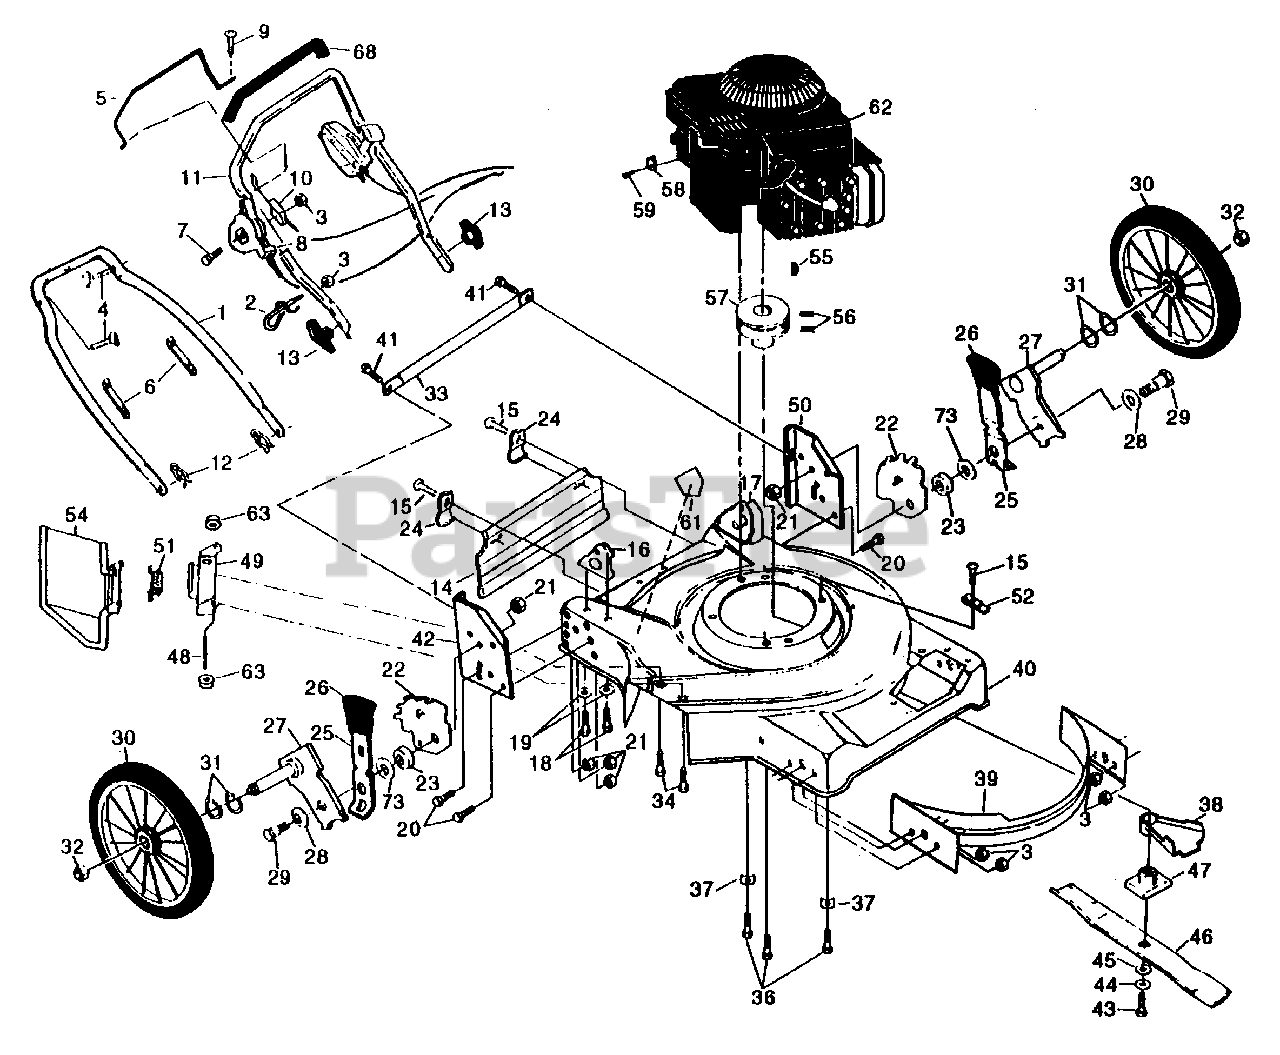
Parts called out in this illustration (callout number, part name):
1	Lower Handle (AYP part number)
2	Rope Guide
3	Locknut 1/4-20 (AYP part number)
4	Handle Bolt (AYP part number)
5	Control Bar (AYP part number)
6	Wire Tie (AYP part number)
7	Hex Washer Head Screw 1/4-20 x 2-1/8 (AYP part number)
8	Throttle Control
9	Pan Head Hi/Lo Screw #10-16 x .63 (AYP part number)
10	Engine Zone Cable
11	Upper Handle (AYP part number)
12	Hairpin Cotter (AYP part number)
13	Handle Knob (AYP part number)
14	Rear Skirt (AYP part number)
15	Hex Head Screw #10 (AYP part number)
16	Handle Bracket Assembly (Right) (AYP part number)
17	Handle Bracket Assembly (Left) (AYP part number)
18	Screw 5/16-18 x 3/4 (AYP part number)
19	Washer (AYP part number)
20	Bolt, Hex Head 3/8-16 x 3/4 (AYP part number)
21	Locknut (AYP part number)
22	Wheel Adjusting Bracket (R.R.) (AYP part number)
23	Spacer (AYP part number)
24	Skirt Bracket (AYP part number)
25	Selector Spring (AYP part number)
26	Selector Knob
27	Axle Arm Assembly (AYP part number)
28	Rear Spring Washer (AYP part number)
29	Shoulder Bolt 3/8-16 (AYP part number)
30	Wheel & Tire Assembly (Rear) (AYP part number)
31	Wave Washer (AYP part number)
32	Nut (AYP part number)
33	Rod Support (AYP part number)
34	Hex Head Thread Rolling Screw w/Sems 1/4-20 x 3 (AYP part number)
36	Thread Rolling Screw 3/8-16 x 1 (AYP part number)
37	Engine Washer (AYP part number)
38	Debris Shield
39	Front Baffle (AYP part number)
40	Mower Housing Kit (Inc.61)
41	Screw (AYP part number)
42	Wheel Support Bracket R.H. (AYP part number)
43	Hex Head Screw 3/8-24 x 1-3/8 Gr. 8
44	Helical Washer 3/8 (AYP part number)
45	Hardened Washer (AYP part number)
46	22" Blade (AYP part number)
47	Blade Adapter
48	Hinge Rod (AYP part number)
49	Housing Bracket (AYP part number)
50	Wheel Support Bracket L.H. (AYP part number)
51	Torsion Spring (AYP part number)
52	Guide Clip (AYP part number)
54	Discharge Guard
55	Hi-Pro Key (AYP part number)
56	Set Screw (AYP part number)
57	Engine Pulley (AYP part number)
58	Cable Clamp (AYP part number)
59	Screw #10 x 5/8 (AYP part number)
61	Danger Decal (AYP part number)
63	Push Nut (AYP part number)
68	Handle Grip (AYP part number)
73	Flat Washer 3/8 (AYP part number)
